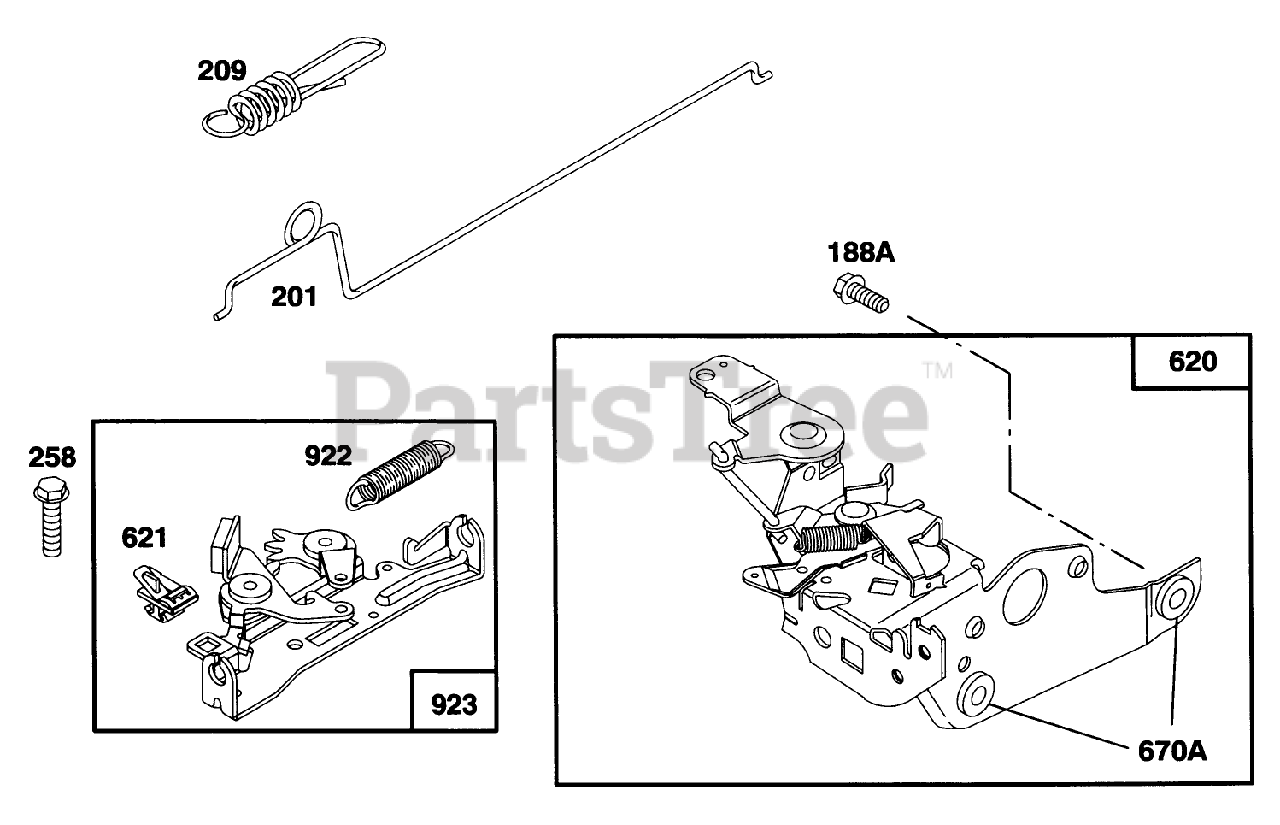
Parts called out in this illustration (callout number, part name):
188A	Screw-Hex.
201	Link-Govemor
209	Spring-Governor
258	Screw-Sem
620	Bracket-Carburetor
621	Switch
670A	Spacer
922	Brake Spring
923	Brake
